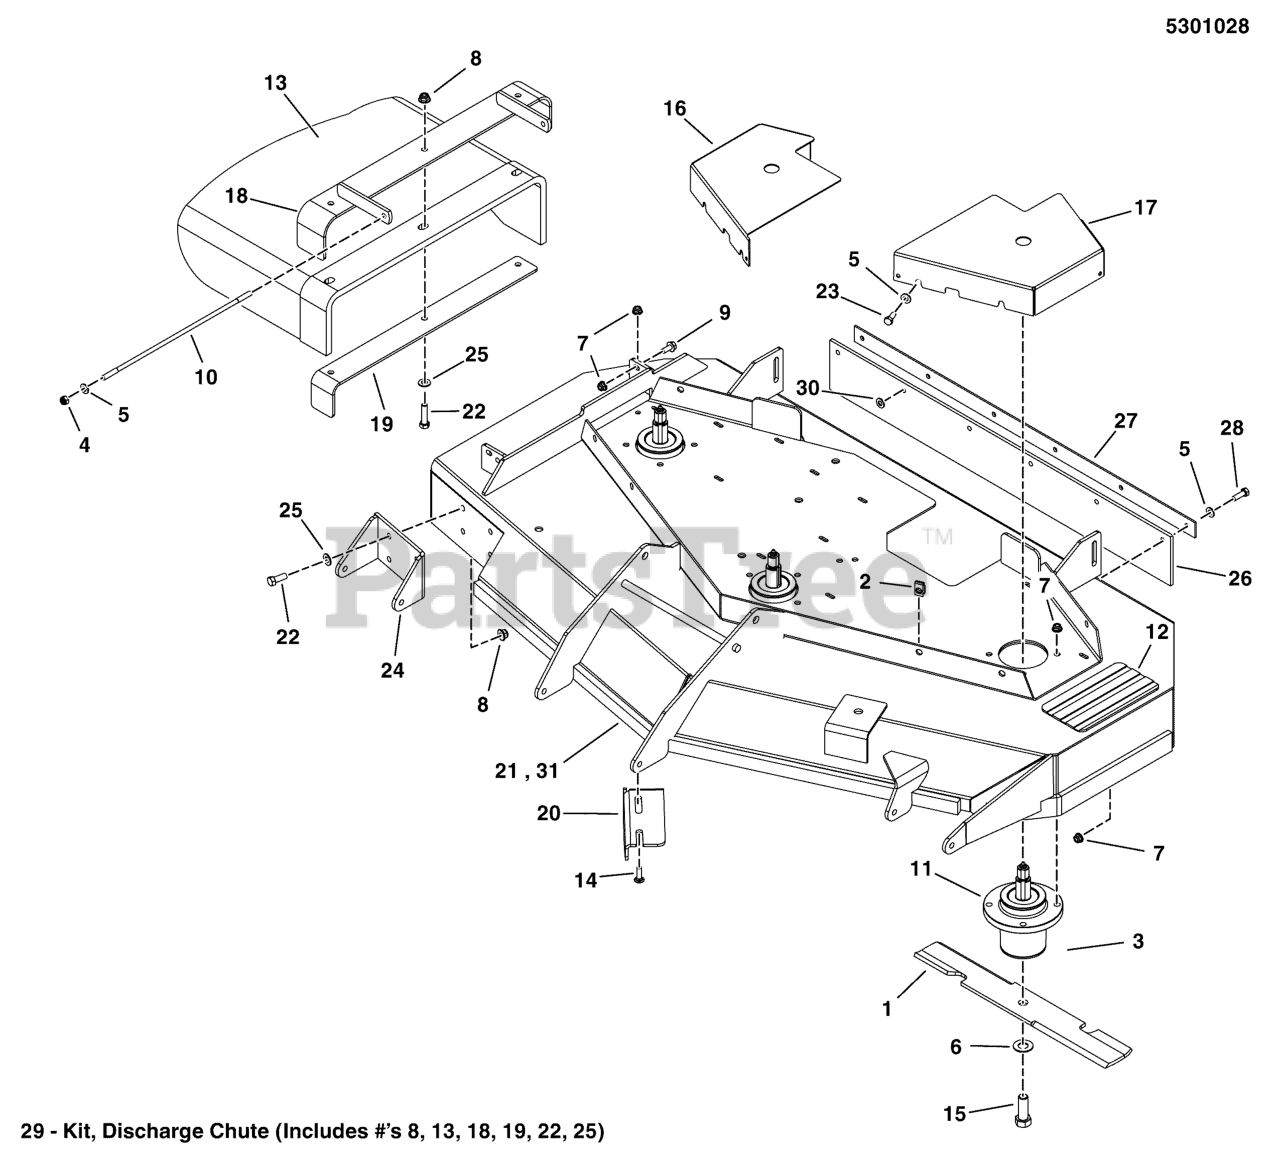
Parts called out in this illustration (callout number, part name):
1	BLADES, SET OF THREE (3); 16.25 X.25 X 2.5, 1 X 3.5
2	BODY CLIP, 5/16-18-7GA MATERIAL
3	BOLT, 5/16-18 X 1 1/4 FLANGE
4	NUT, 5/16-24 HEX NYLON LOCK
5	WASHER, 5/16" SAE
6	WASHER, 5/8 GRADE 8, YZ
7	NUT, 5/16-18 HEX NYLOCK FLANGE
8	NUT, 3/8-16 HEX NYLOCK FLANGE
9	BOLT, 5/16-18 X 3/4 GD5
10	ROD, 5/16 X 13.75, TBE, CZ
11	ASSM, SPINDLE, LOW PROFILE
12	SAFETY WALK, 4.00 X 7.50
13	CHUTE, DISCHARGE, RUBBER, 44/48/52
14	BOLT, 5/16-18 X 3/4, CARRIAGE
15	BOLT, 5/8-11 X 1-3/4 GD8
16	GUARD, 48 DECK - RH -RED
17	GUARD, 48 DECK - LH -RED
18	WELD, FRAME, CHUTE, 44/48/52 - BLK
19	SUPPORT,DISCHARGE CHUTE - BLK
20	PLATE, DEFLECTOR - BLK
21	DECK SHELL W/ DECALS, 48 - S150X
22	BOLT, 3/8-16 X 1-1/4" GD5 CZ
23	BOLT, 5/16-18 X 3/4 GD5
24	WELD,BRACKET, ANTI SCALP - RED
25	WASHER, 3/8 SAE
26	FLAP, RUBBER, 48"
27	PLATE, SUPPORT, 48 - BLK
28	BOLT, 5/16-18 X 1 GD5 YZ
29	KIT, DISCHARGE CHUTE
30	5/16 PUSH-ON NUT RETAINER, STL, CZ
31	DECK SHELL W/ DECALS, 48, S150XT
